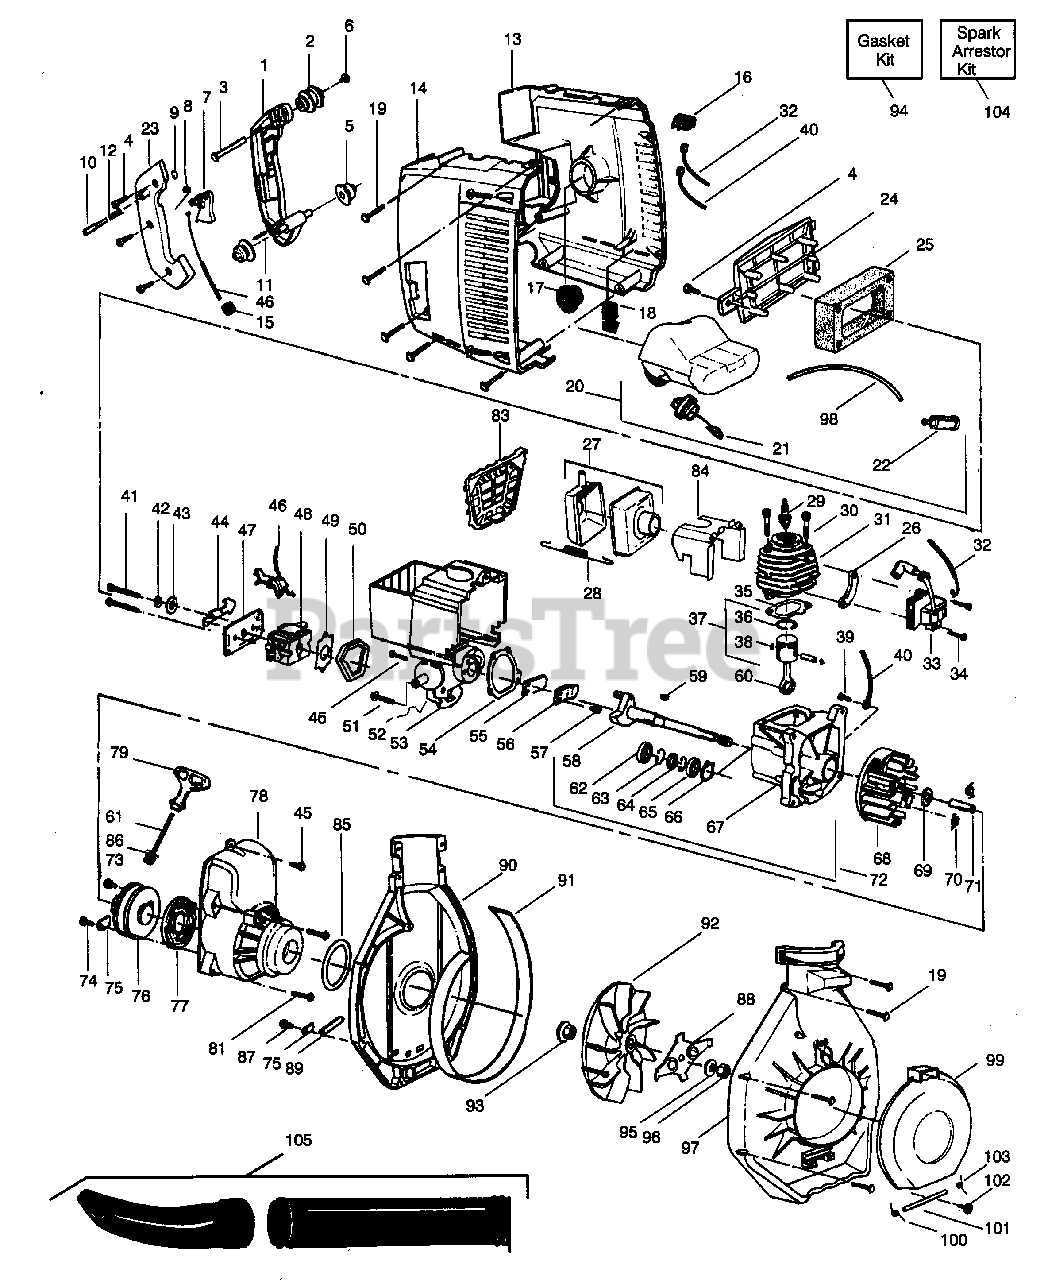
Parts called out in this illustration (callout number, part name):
1	Handle
2	Front Isolator
4	Screw-Handle
5	Rear Isolator
9	"C" Clip
10	Throttle Lock Button
12	Spring-Throttle Lock
13	Shroud-Left
14	Shroud-Right
15	Grommet-Carb.
16	Switch Kit
17	Isolator-Engine Mount
18	Isolator-Tank
19	Screw-Shroud/Blower Hsg.
20	Fuel Tank Ass'y.
21	Fuel Cap (Incl. O'Ring)
22	Fuel Pick-up Ass'y.
23	Handle Cover/Throttle Lock Ass'y. (Incl. 9, 10 & 12)
24	Cover-Air Filter
25	Air Filter
26	Spacer (Model SV22 only)
29	Spark Plug
31	Model SV22
31	Model SV30
32	Lead Wire
33	Ignition Module
34	Model SV22
34	Model SV30
35	Gasket-Cylinder
36	Model SV22 (1 ring)
36	Model SV30 (2 rings)
37	Model SV22
37	Model SV30
38	Retainer
40	Ground Wire
42	Wave Washer
43	Spacer-CHoke
44	Choke Shutter
45	Screw-Reed
46	Throttle Cable Assembly
47	Plate-Air Filter
48	Carburetor Ass'y. (WT-141A) (Incl. Limiter Cap)
49	Gasket-Carb
50	Seal-Reed Block
52	Ground Wire-Static
53	Reed Block
54	Gasket-Reed Block
55	Reed Valve
56	Reed Stop
58	Crankshaft
60	Model SV22
60	Model SV30
61	Rope Kit
62	Inner Bearing
63	Retaining Ring-Crankcase
64	Crankshaft Seal
65	Outer Bearing
66	Retaining Ring-Crankshaft
67	Crankcase Ass'y (Incl. 62-65)
68	Flywheel Ass'y. (Incl. 70)
69	Washer
71	Spacer-Flywheel
72	Crankcase/Crankshaft Assy. (Incl. 58, 62-67)
75	Retainer
76	Starter Pulley (Incl. 73)
77	Starter Spring
78	Fan Housing Kit (Inc.61,71,73-76,79,86)
79	Starter Handle
82	Hex Wrench 5/32"
83	Muffler Guard Kit (Incl. 82)
84	Air Baffle
85	"O" Ring
87	Screw
88	Mulch Blade
89	Roll Pin
90	Blower Housing (Upper)
92	Impeller (Incl. 93)
93	Hub-Impeller
94	Gasket Kit
97	Blower Housing (Lower) (Incl. 99-103)
98	Line Kit
99	Door-Inlet
100	Spring-Right
103	Spring-Left
104	Spark Arrestor Kit
105	Ass'y-Tube and Nozzle
